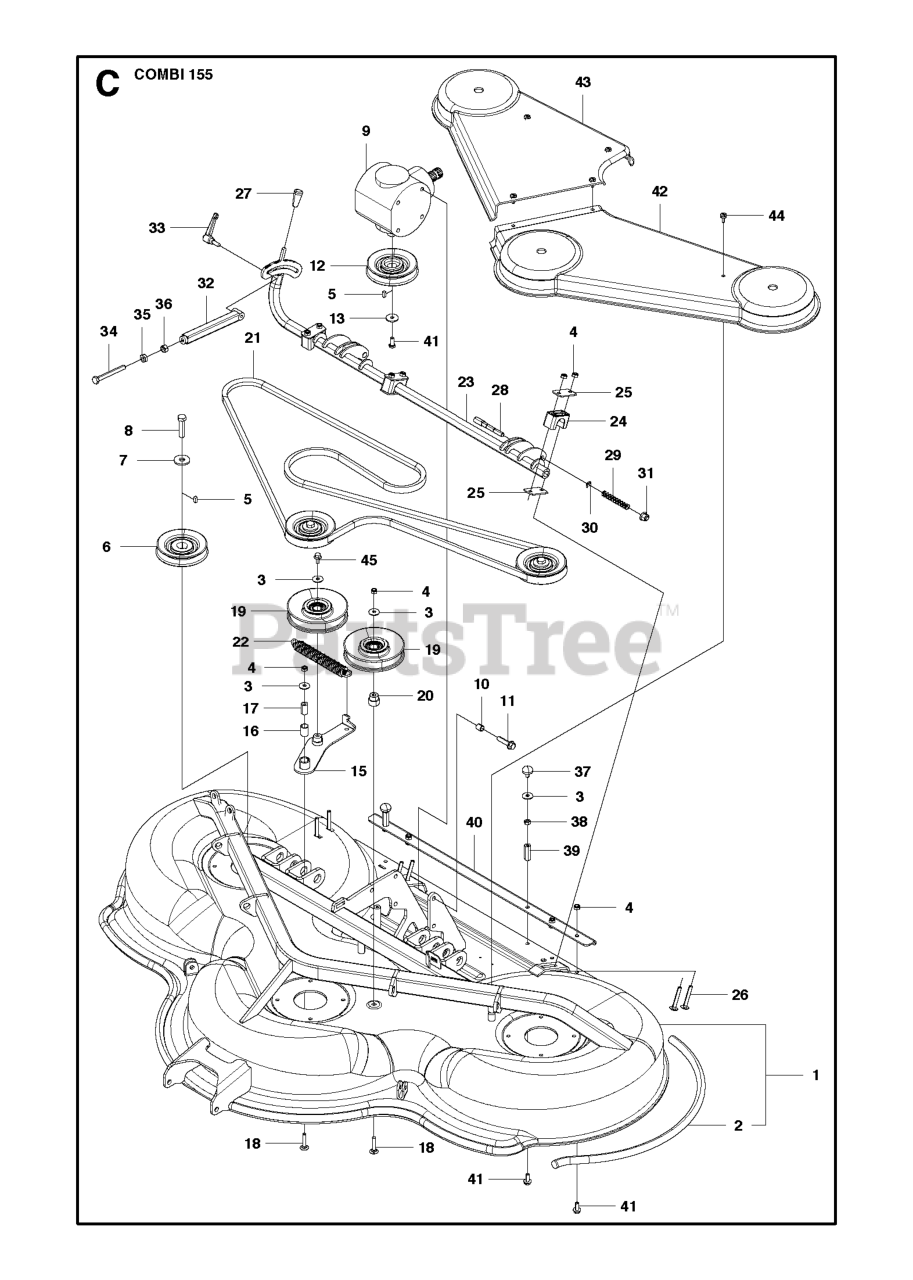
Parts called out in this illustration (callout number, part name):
4	LOCKNUT M8
9	BEVEL GEAR
12	PULLEY SPB DP106
15	BELT TENSIONER CUTTING DECK
18	Screw Mvbf 8 X 40
22	DRAW SPRING L=122
32	PARALLEL ROD REPLACE -01
33	TURNING KNOB M 8
35	NUT
36	NUT
37	ANTIVIBRATION ELEMENT
38	NUT
40	REINFORCING PLATE DECK SHELL
42	BELT COVER C155 L_GREASEABLE
43	BELT COVER C155 R_GREASEABLE
45	BOLT FLANGE - M8X16
